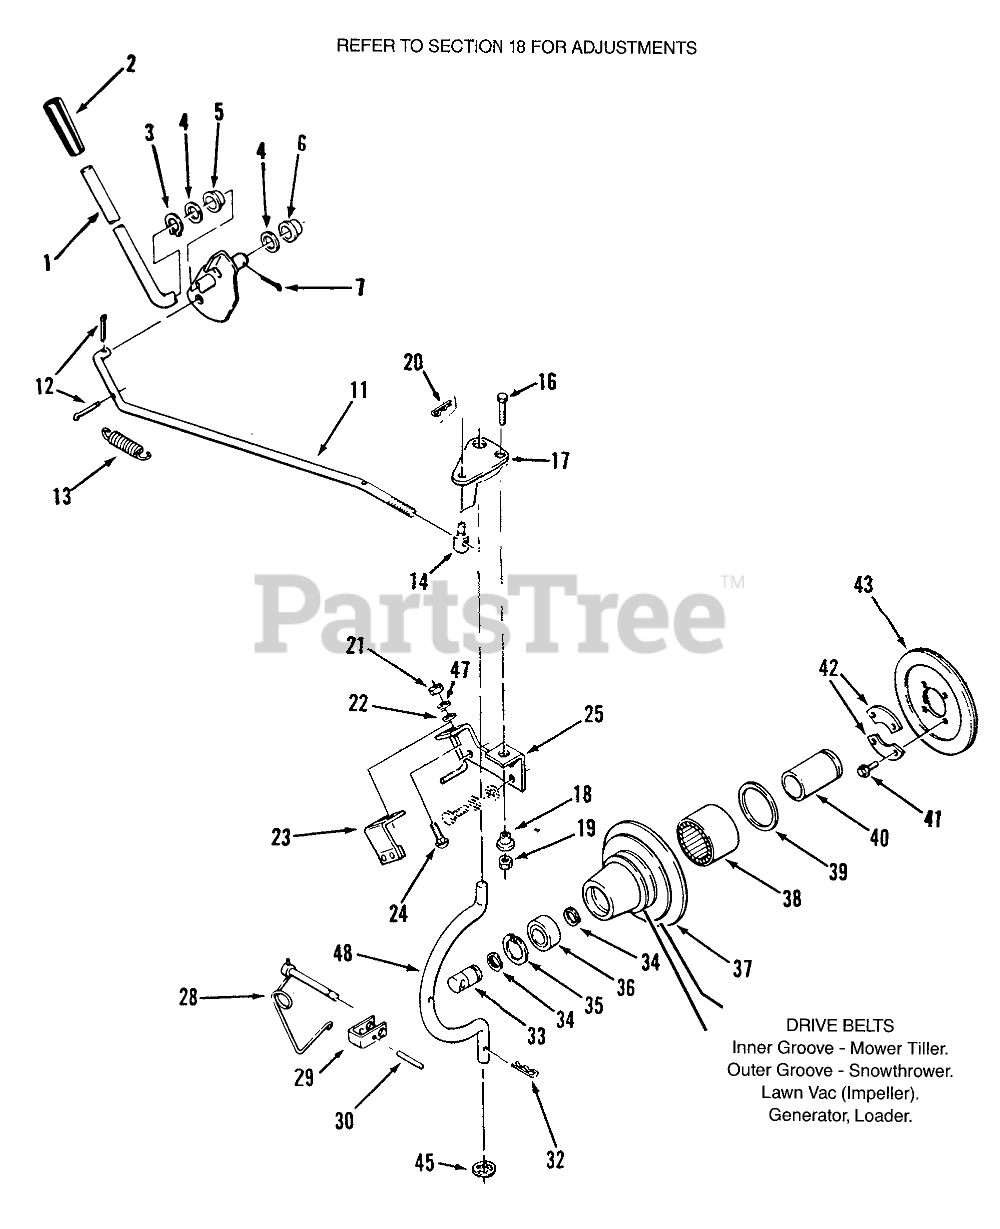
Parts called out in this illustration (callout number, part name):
1	ASSY PTO CLUTCH LEVE
2	GRIP
3	Grip Ring
4	SHIM-WASHER
5	BUSHING-NYLINER
6	NYLINER BUSHING
7	Pop Rivet
11	ROD-PTO CLUTCH
12	Pop Rivet
13	SPRING
14	TRUNNION
16	Bolt
17	PLATE
18	SPACER-LIFT LINK
19	NUT
20	Hairpin Cotter
21	Nut
23	ASM-Bracket
24	Bolt-Carriage
25	Bracket-Engine
28	LOCKING PIN ASM
29	CLEVIS
32	Hairpin
33	SHAFT-PTO
34	RING-SNAP, EXTERNAL
35	Ring-Snap
36	BEARING-BALL
37	Housing-Clutch
38	BRG-NEEDLE OPEN END
39	SEAL-OIL
40	RACE-BEARING
41	H H C S
42	RETAINER
43	Facing-Clutch
45	RING-REINFORCED CIRC
47	Washer
48	ROD-HOUSING
